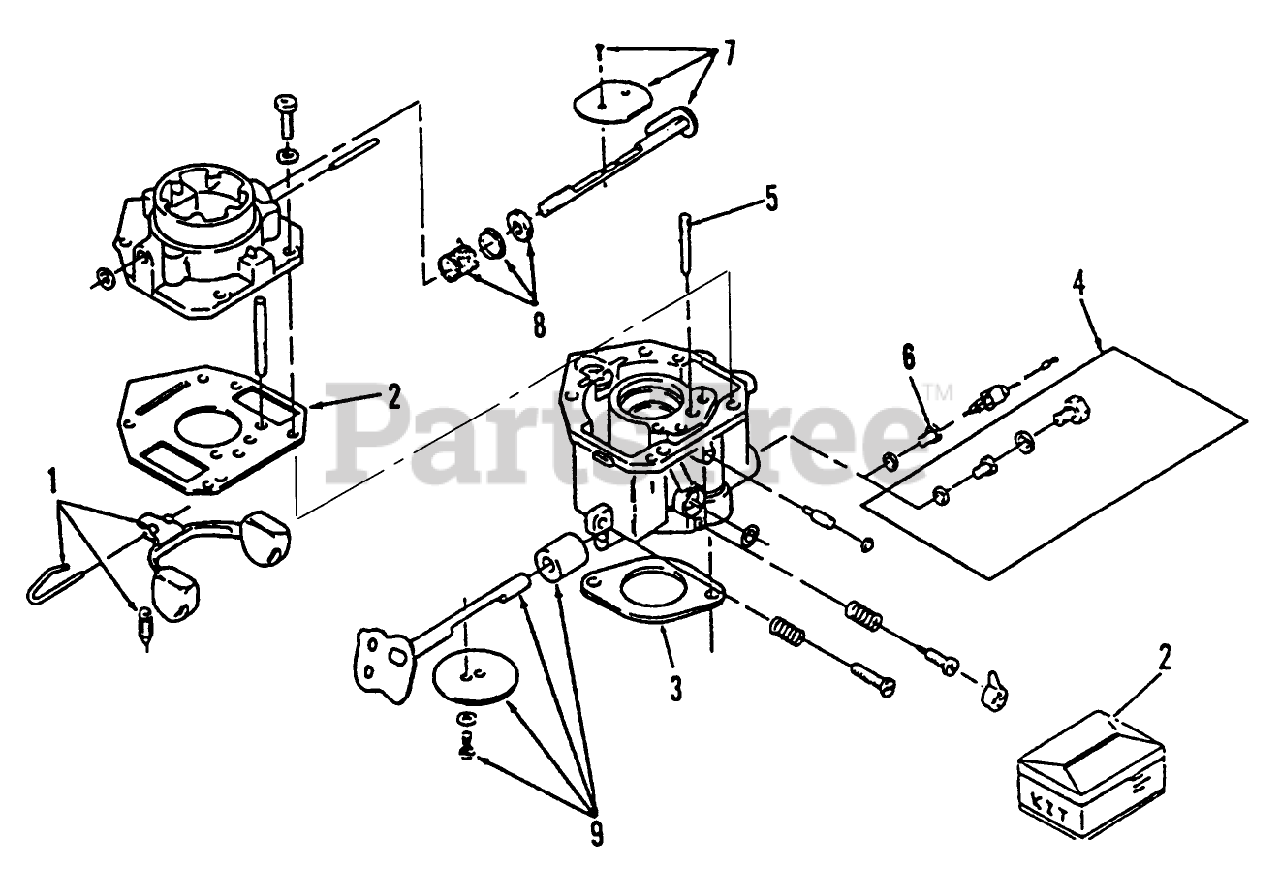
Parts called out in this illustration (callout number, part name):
2	REPAIR KIT
3	GASKET-CARBURETOR
8	CHOKE-LEVER KIT
